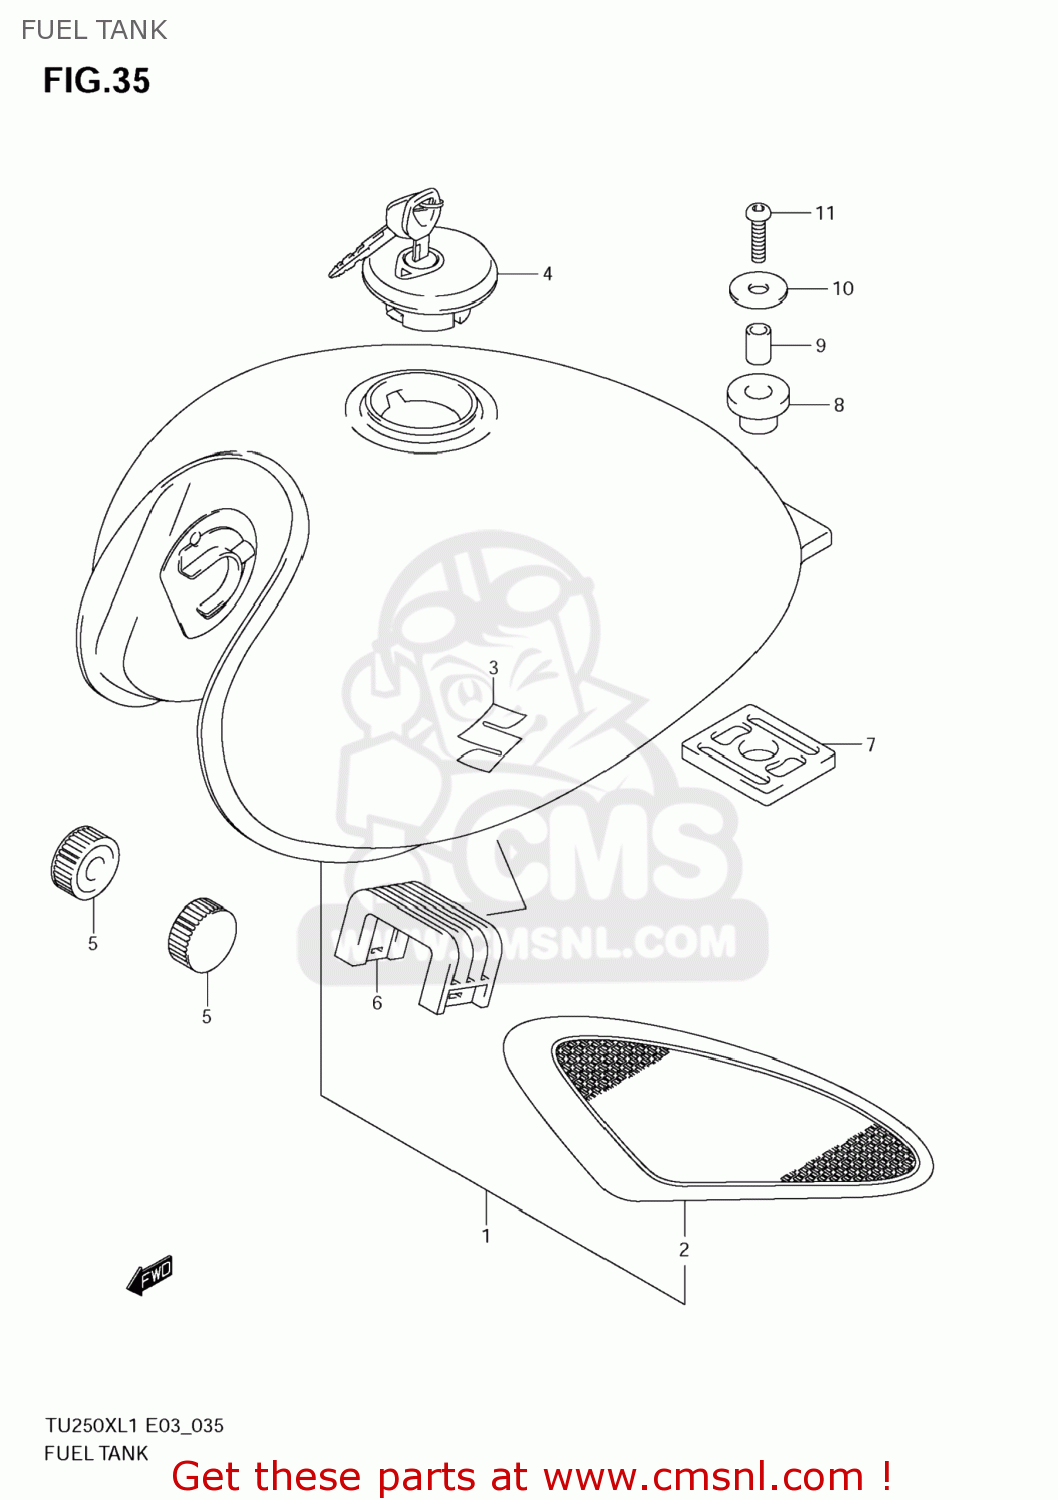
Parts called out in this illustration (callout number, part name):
1	TANK ASSY, FUEL
2	TAPE SET,FUEL TANK
3	EMBLEM,S
4	CAP SET,FUEL TANK
5	CUSHION
6	CUSHION,TANK UPR FR
7	CUSHION,FUEL TANK RR LWR
8	CUSHION,FUEL TANK RR UPR
9	SPACER (8.2X12.5X23.5)
10	WASHER(8.5X33X1.5)
11	BOLT
